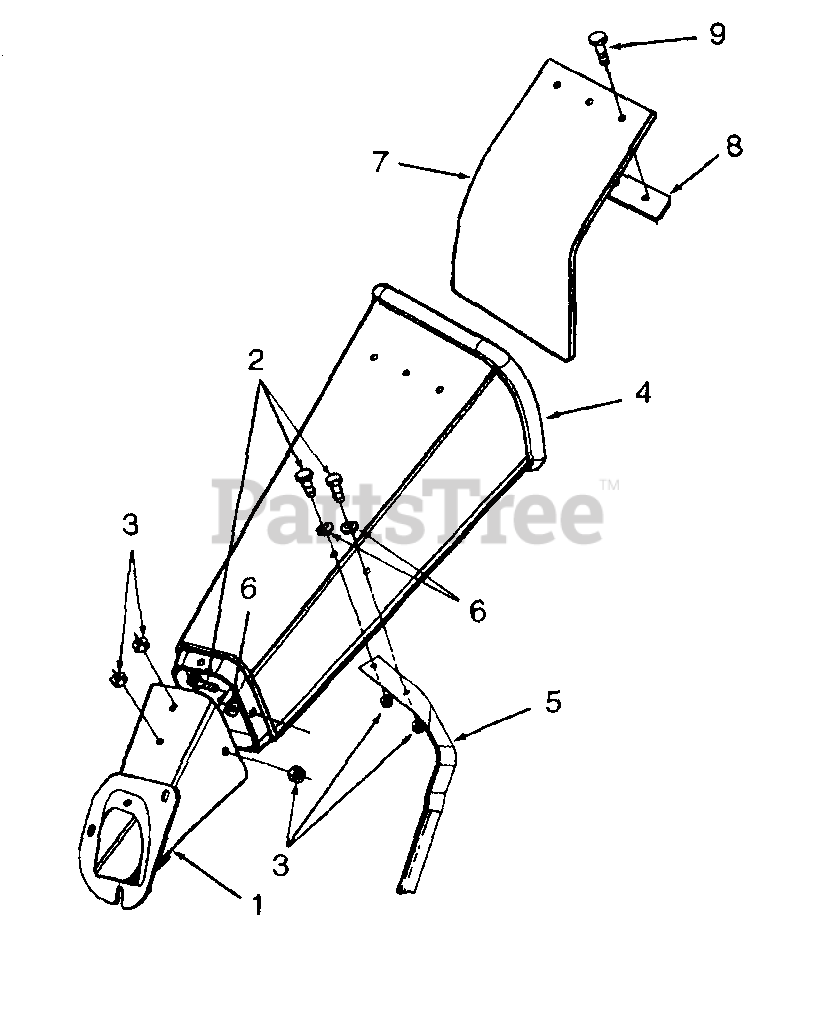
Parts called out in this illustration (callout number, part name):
1	Chute Assembly, Chipper
2	Screw, Hex Cap, 1/4-20 x .625
3	Nut, Hex Flange Lock, 1/4-20
4	Chute, Chipper
5	Bracket, Chipper Chute Support
6	Washer, Flat, .28 x .74 x .63
7	Flap, Chipper Chute
8	Strip, Chute Flap
9	Rivet, Pop, .156 x .504
